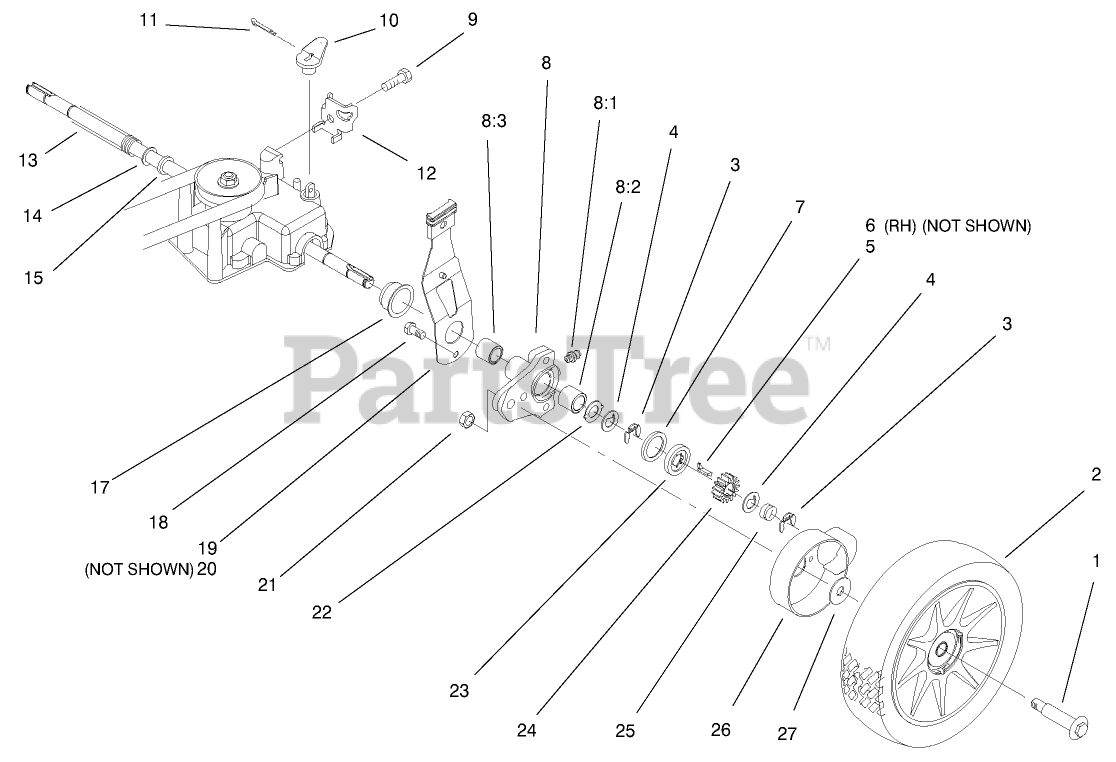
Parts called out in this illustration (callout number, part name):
1	BOLT-SHOULDER
2	WHEEL AND GEAR ASM
3	RING-CLIP, LOCKING
4	WASHER-THRUST, KEYED
5	KEY-ROCKING, LH
6	KEY-ROCKING, RH
7	RING-FRICTION
8	REAR HEIGHT ADJUSTMENT ARM ASM
8:1	FITTING-GREASE
8:2	BUSHING
8:3	BUSHING
9	SCREW-HWHTF
10	LEVER-SHIFT
11	PIN-COTTER
12	CLAMP-CABLE
13	COVER-SHAFT, DRIVE
14	WASHER
15	WASHER
17	RING-ISOLATOR
18	SCREW-HWH
19	LH REAR SPRING ARM ASM
20	RH REAR SPRING ARM ASM
22	WASHER-ARM, PIVOT
23	WASHER-CLUTCH
24	GEAR-PINION
25	SPRING-COMPRESSION
26	COVER-WHEEL
27	WASHER-STEPPED
